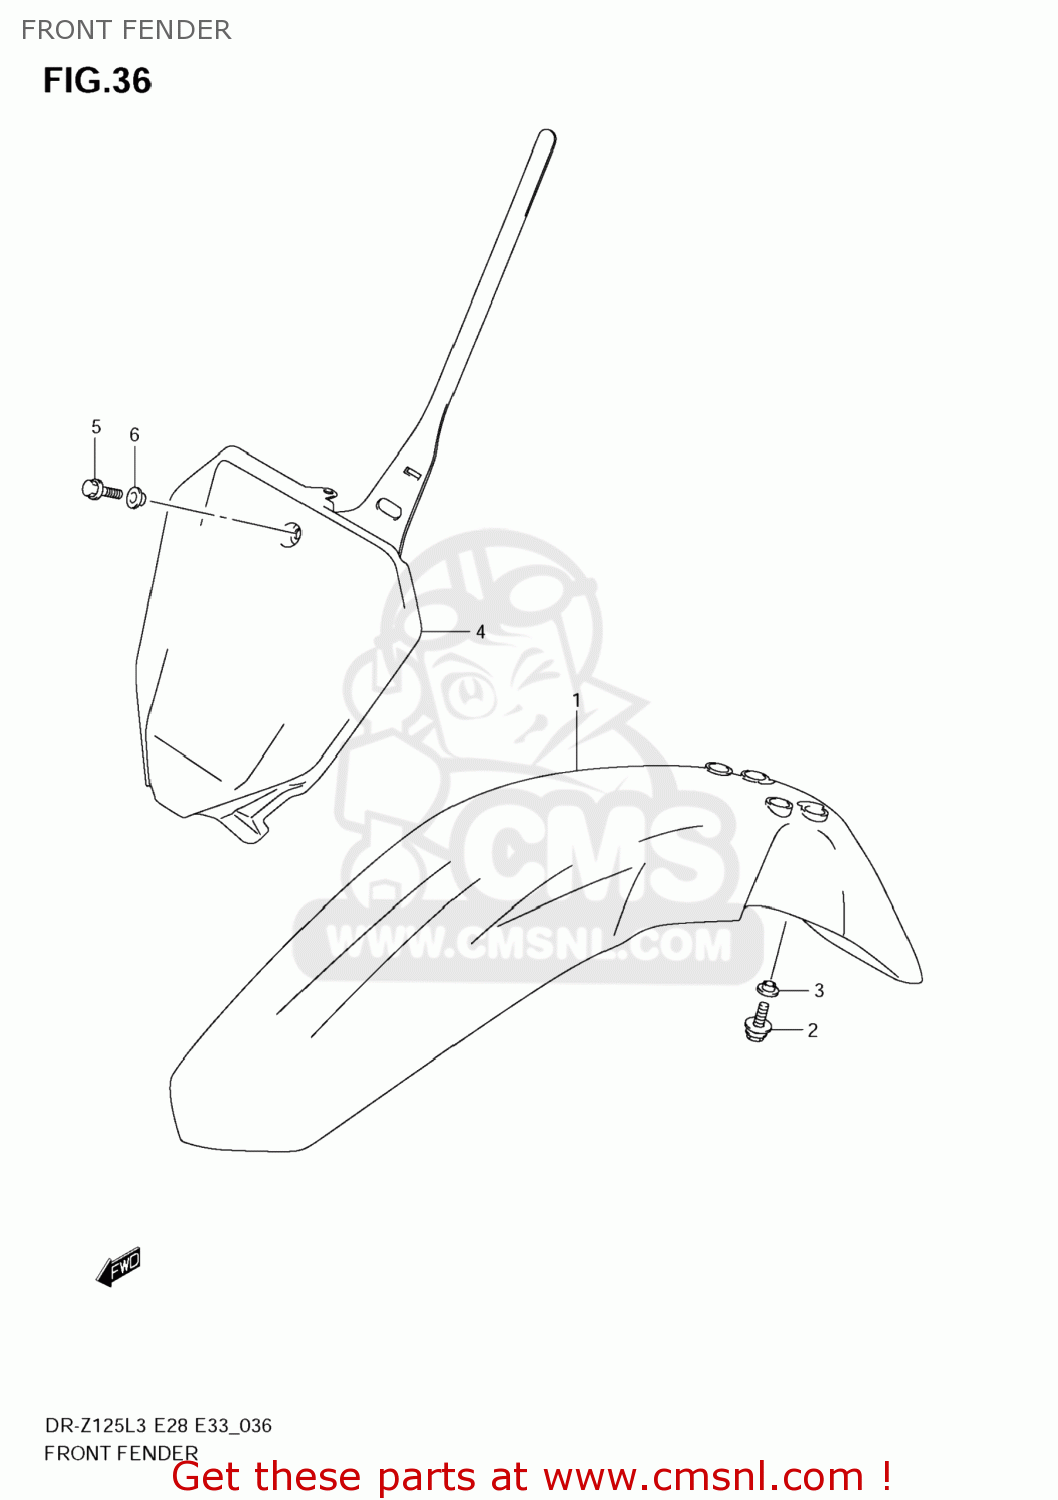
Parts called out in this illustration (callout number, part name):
1	FENDER,FR
2	BOLT(6X16)
3	WASHER
4	PLATE,NUMBER FR
5	BOLT
6	WASHER
